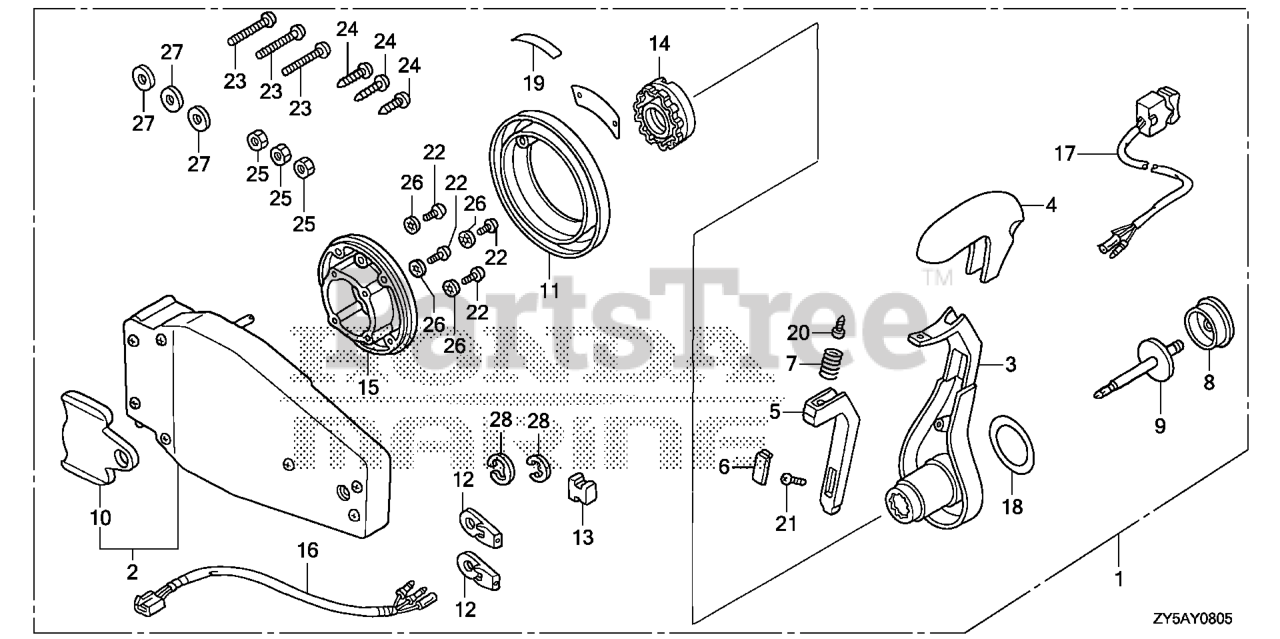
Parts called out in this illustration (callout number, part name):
1	BOX KIT, REMOTE CONTROL (FLUSH MOUNT)(L)
2	HOUSING ASSY., L. (INNER) (FLUSH MOUNT)
3	HANDLE, REMOTE CONTROL
4	COVER, GRIP
5	ARM, NEUTRAL LOCK
6	COVER, LOCK ARM
7	SPRING, NEUTRAL LOCK ARM
8	BUTTON, THROTTLE
9	SHAFT, THROTTLE BUTTON
10	PLATE, DWELL
11	COVER ASSY.
12	TERMINAL, CABLE
13	SPACER, CABLE CLAMP
14	HOLDER, NEUTRAL LOCK
15	BASE
16	SUB-HARNESS ASSY., POWER TRIM-TILT (C)
17	SWITCH ASSY., POWER TRIM-TILT (C)
18	MARK, HANDLE FLUSH MOUNT
19	MARK, FLUSH MOUNT
20	SCREW, PAN (5X16)
21	SCREW, TRUSS (4X12)
22	SCREW, PAN (5X30)
23	SCREW, PAN (6X35)
24	SCREW, TAPPING (6X30)
25	NUT, HEX. (6MM)
26	WASHER, LOCK (5MM)
27	WASHER, PLAIN (6MM)
28	E-RING (6MM)
